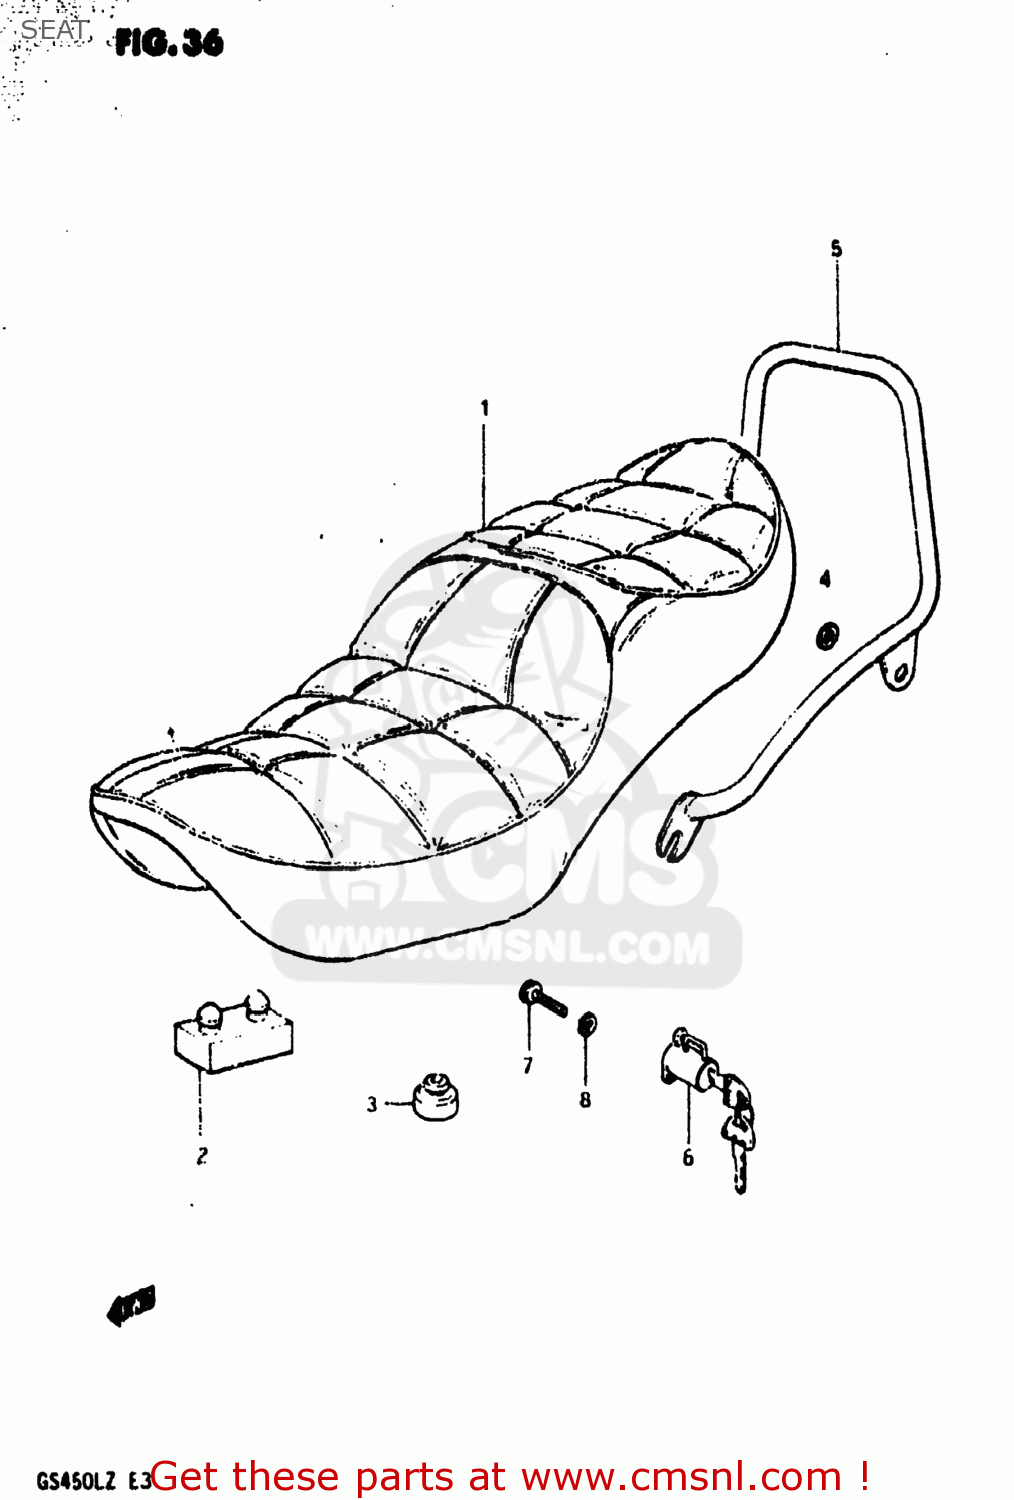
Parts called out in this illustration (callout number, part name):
1	SEAT ASSEMBLY
2	CUSHION
3	CUSHION
4	WASHER
5	HANDLE,PILLION RIDER
6	LOCK ASSEMBLY,HELMET
7	BOLT 6X11
8	LOCK WASHER
